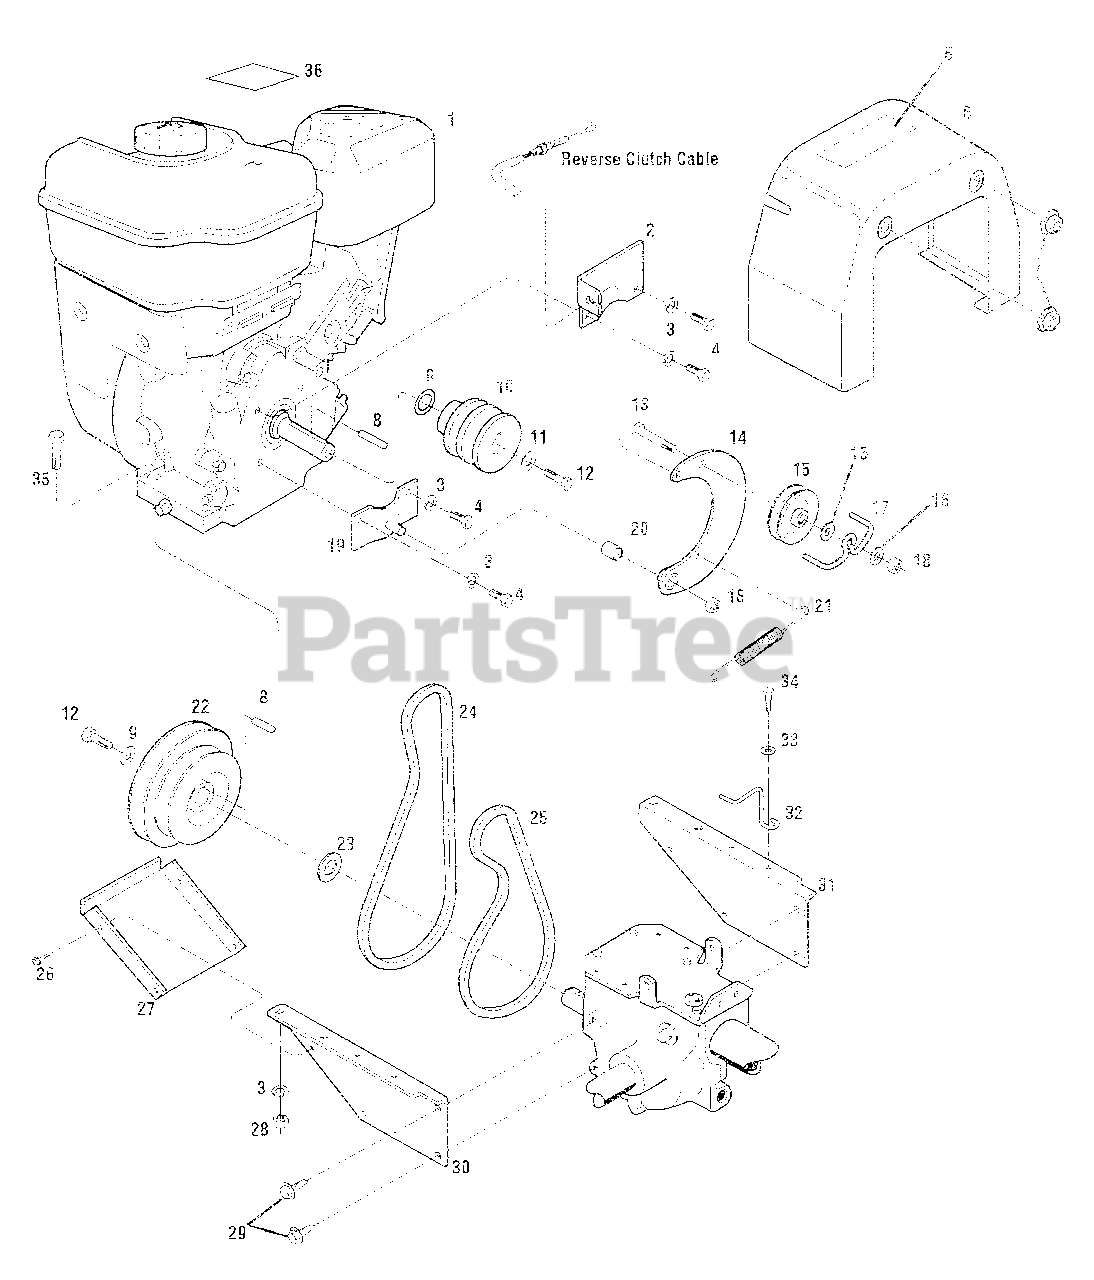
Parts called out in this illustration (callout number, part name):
1	Engine - 6HP, standard recoil start
2	Bracket, Clutch Cable
3	Lockwasher-5/16
4	Screw-hex hd., 5/16-24 x 1/2
5	Decal-Hot surfaces/belt warning
6	Cover-
7	Nut 5/16-18, Flange Lock
8	Key-3/16 x 1-1 /2
9	Washer-Disc Spring
10	Pulley, Engine Drive
11	Washer, Belleville
12	Screw-hex hd., 5/16-24 x 1-1/8
13	Screw-hex hd., 5/16-18 x 2
14	Reverse Idler Arm
15	Pulley, Reverse Idler
16	Washer, Flat, 5/16
17	Belt Guide
18	Locknut, 5/16-18
19	Bracket, Reverse Idler
20	Bushing
21	Spring, Reverse Return
22	Pulley, Transmission
23	Support Washer
24	Reverse Drive Belt
25	Forward Drive Belt
26	Screw-hex hd., #10-32 x 1/2, self-tapping
27	Guard, Belts/Pulleys
28	Hex Nut, 5/16-18
29	Screw-flanged hex hd., 5/16-18 x 3/4
30	Support Bracket-engine, left side
31	Support Bracket-engine, right side
32	Belt Guide
33	Washer-flat, 1/4
34	Screw-hex hd., self-tapping, 1 /4-20 x 3/4
35	Screw-hex hd., 5/16-18 x 1-1/2
36	Decal-Stabilization
